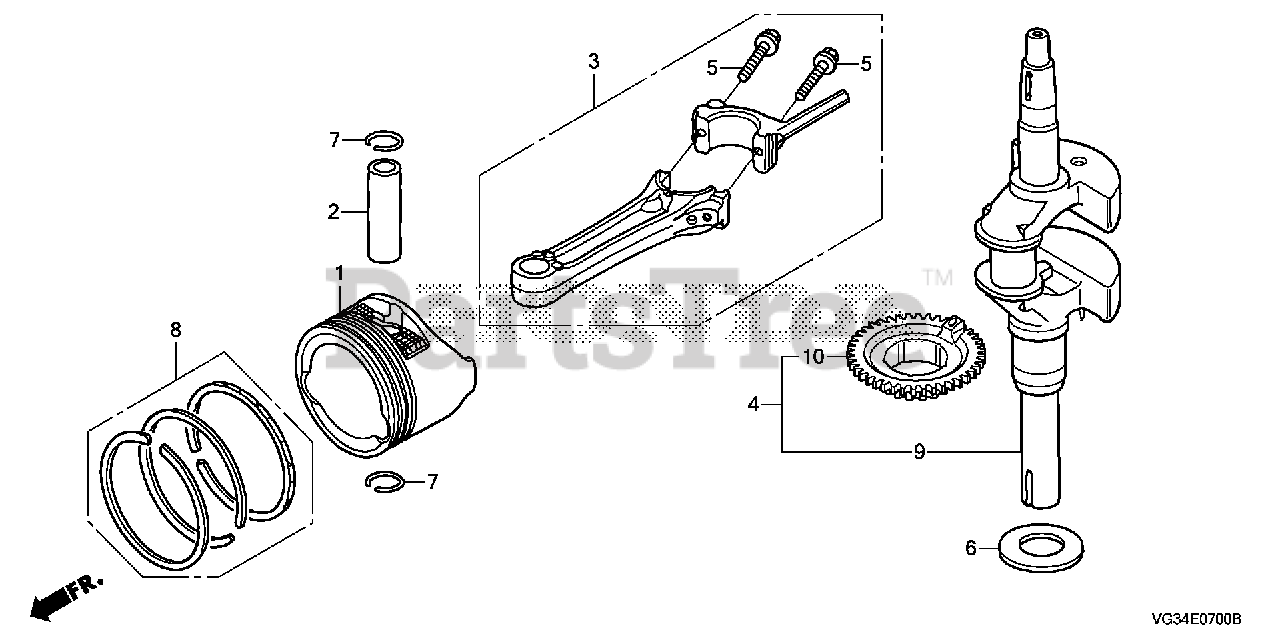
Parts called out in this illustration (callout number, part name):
1	PISTON
2	PIN, PISTON
3	CONN ROD ASSY.
3	ROD ASSY., CONNECTING
5	BOLT, CONNECTING ROD
6	WASHER, THRUST
7	CLIP, PISTON PIN (13MM)
8	RING SET, PISTON (STD) (TEIKOKU)
9	CRANKSHAFT
10	PULLEY, TIMING BELT DRIVE
